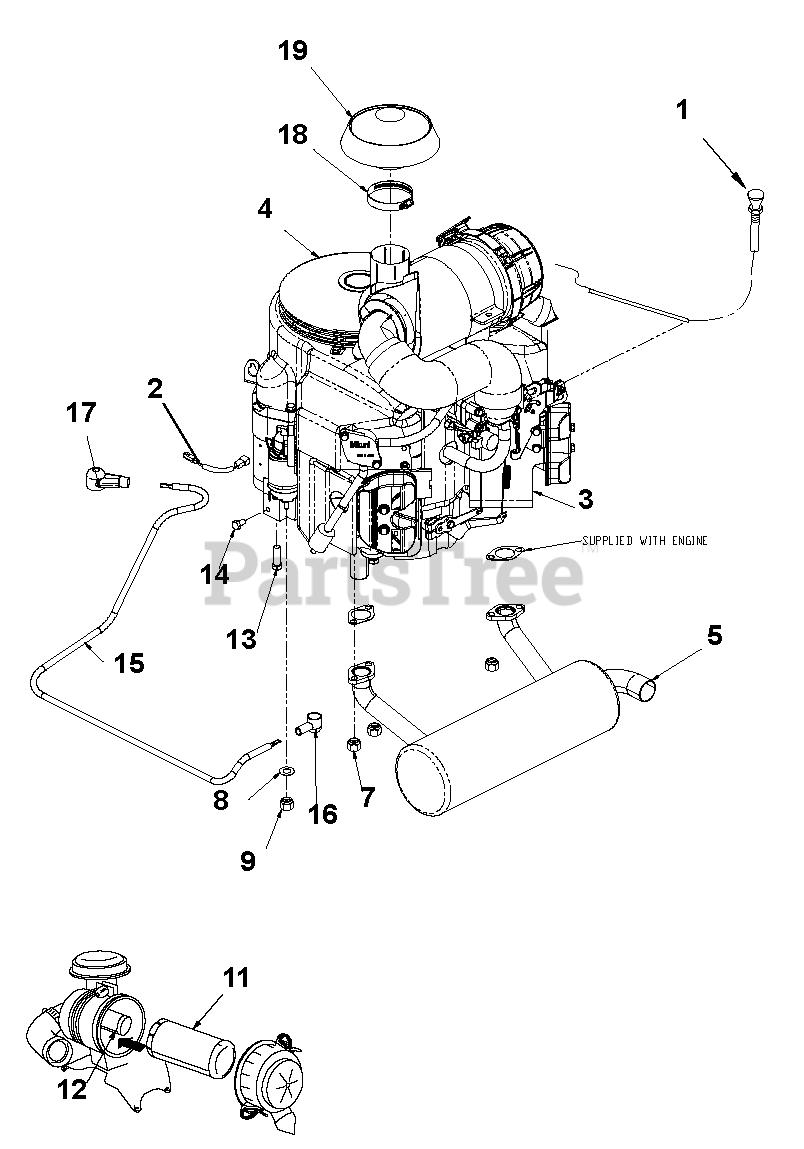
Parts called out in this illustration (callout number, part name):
1	Cable, Choke 48"
2	Lead, Starter Solenoid
3	Oil Filter
4	Engine, Kawasaki 27 HP (992406, 407)
5	Muffler, Kawasaki Horizontal
7	Locknut, 5/16-18 Crown
8	Washer, M8 Spring Lock
9	Nut, M8 x 1.25 Hex GR8.8
11	Filter, Outer Air
12	Filter, Inner Air
13	Bolt, Hex .38-16 x 1.25 FTHG5
14	Bolt, M8 x 1.25 x 14 Hex 8.8
15	Cable, Battery- 42" Positive
16	Boot, Eyelet Terminal
17	Battery Terminal Boot, Red
18	Clamp, Hose 2.75 Diameter Worm
19	Rain Cap, Air Cleaner
